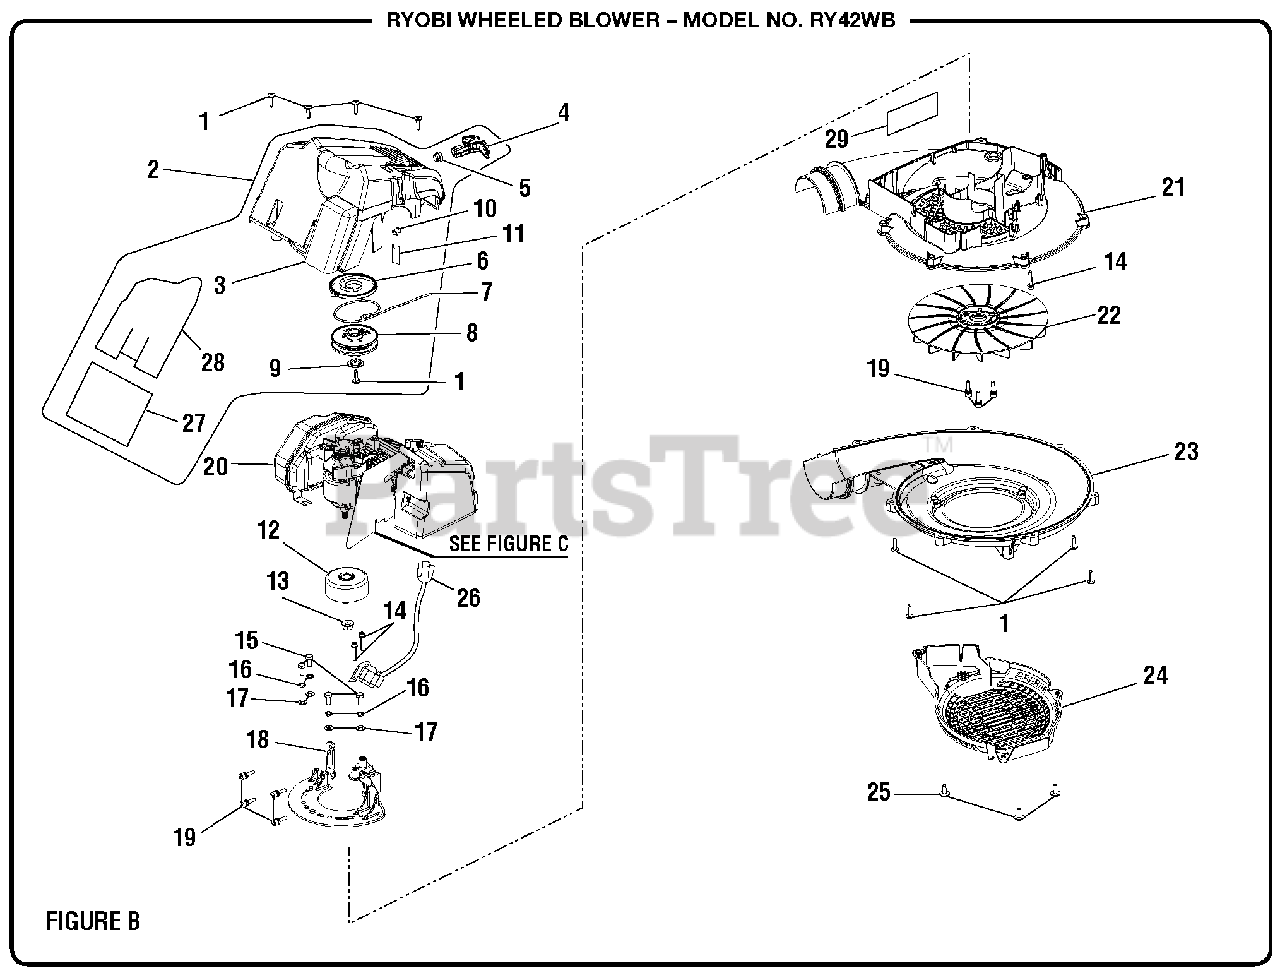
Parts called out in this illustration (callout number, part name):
1	Screw (10-14 x 19 mm, T25 Torx Truss Hd.)
2	Engine Cover w/Starter Assembly
3	Motor Cover
4	Starter Grip
6	Container Spring Assembly
7	Starter Rope
8	Solid Pulley
9	Starter Cap
11	Eyelet Support
13	Flange Lock Nut (M8, Left Hand Threads)
14	Screw w/Washer (M5 x 25 mm, T-25 Torx Pan Hd.)
15	Screw (M6 x 14 mm, Hex Soc. Hd.)
16	Spring Washer (ID6.4 x 1.6t)
17	Washer (OD12.9 x ID6.6 x 1.2t)
18	Engine Mount
19	Screw w/Washers (M5 x 20 mm, Hex Soc. Hd.)
20	Power Head Assembly
21	Inner Volute
23	Outer Volute
24	Intake Cover
25	Screw (10-14 x 18 mm, T25 Torx Pan Hd.)
26	Ignition Module
27	Foil Tape
28	Insulation
29	Heat Shield Tape
